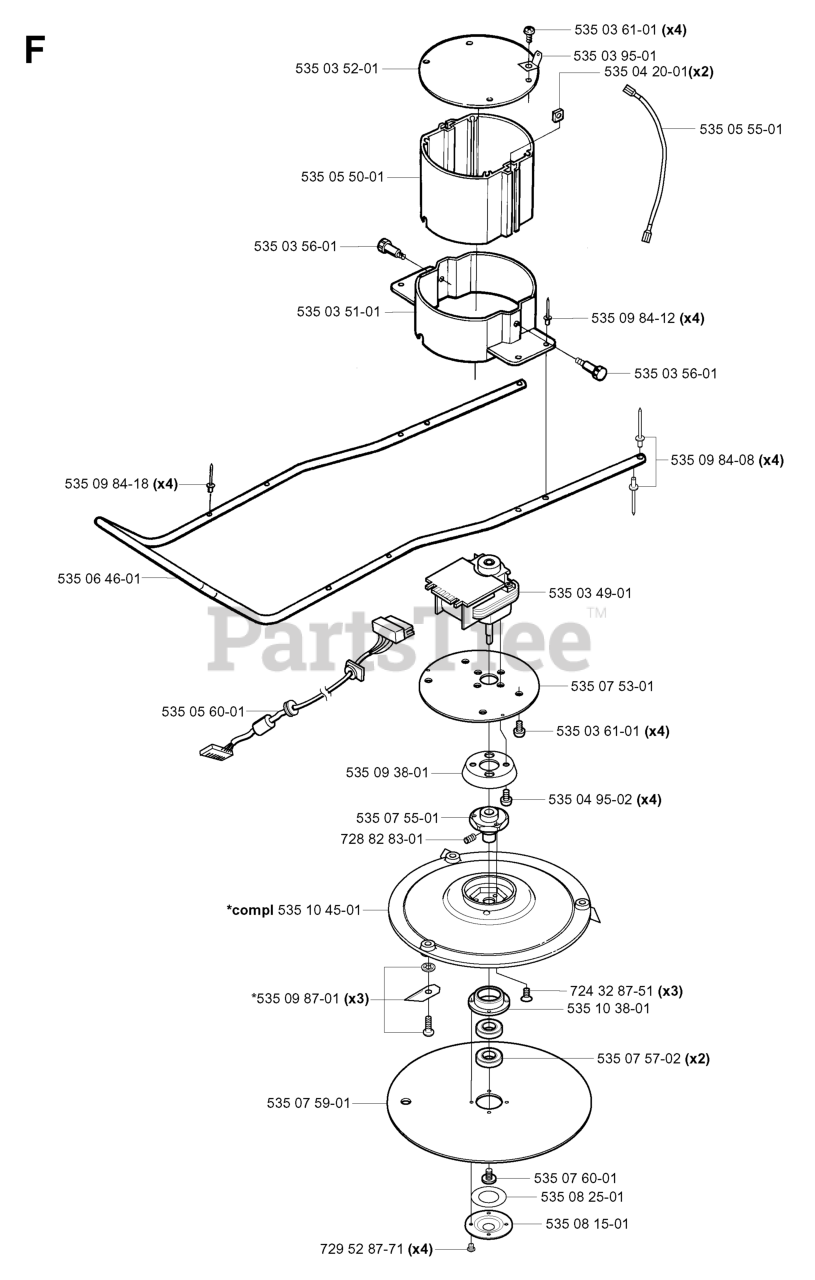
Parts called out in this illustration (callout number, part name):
2	SCREW, IDLE
4	COVER PUMP
6	PUMP DIAPHRAGM
10	SHAFT ASSEMBLY,THROTTLE
14	SCREEN
16	PISTON ASSY
18	LEVER THROTTLE
20	SHAFT ASSEMBLY,CHOKE
29	VALVE INLET
34	SCREW ASSY
36	CHOKE SPRING
37	GASKET KIT
